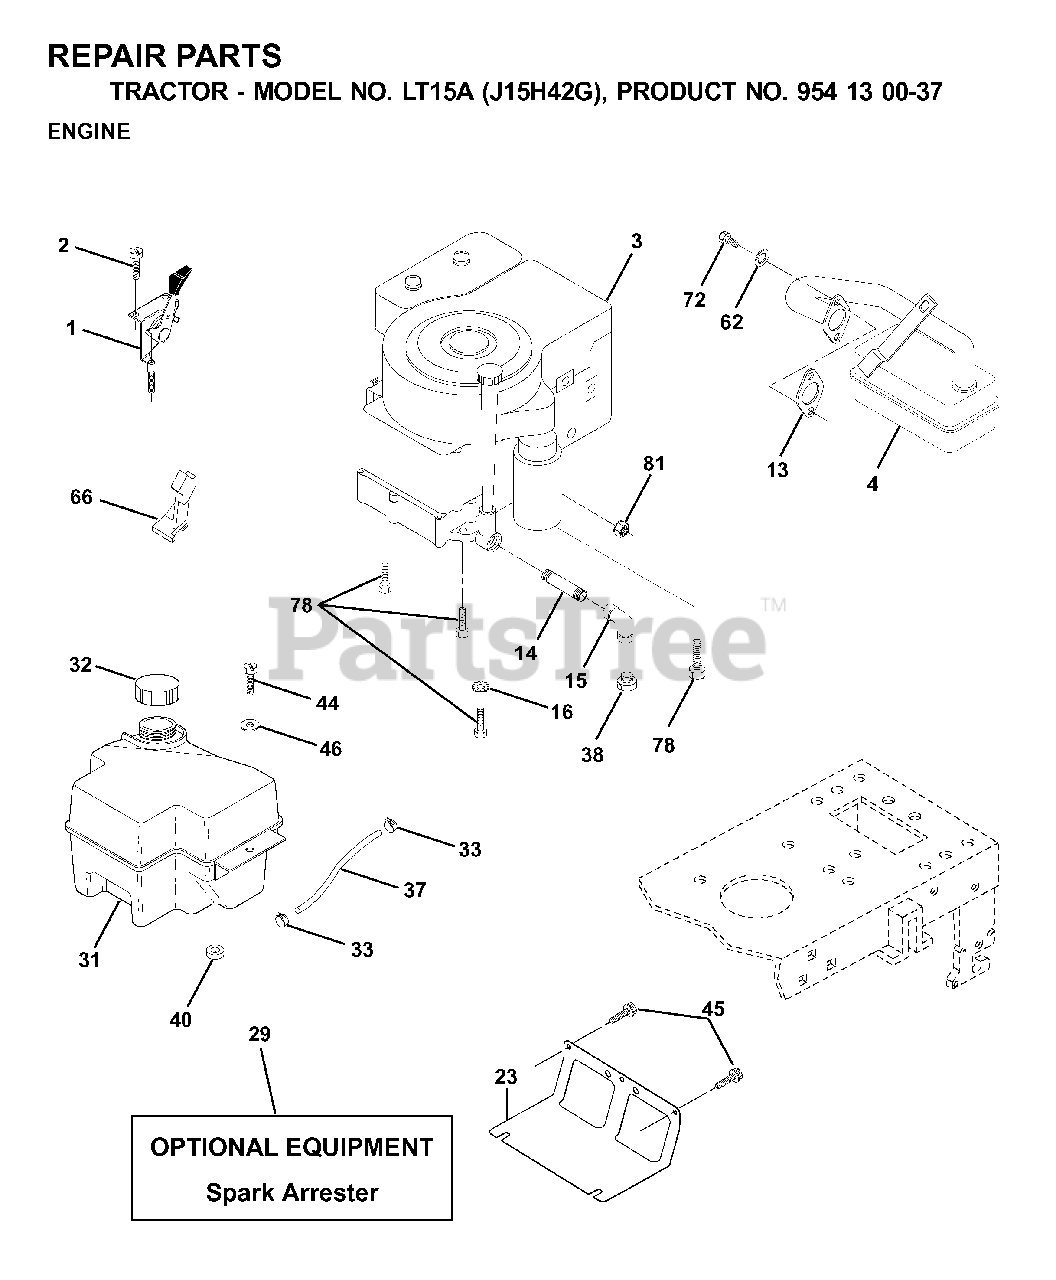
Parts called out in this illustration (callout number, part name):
1	CONTROL
2	SCREW LT
13	REPL BY 532 27 22-93
15	ELBOW
16	LOCKWASHER
23	SHEILD.BROWNING.DBR.GUARD
29	ARRESTER SPARK (OPTIONAL)
31	FUEL TANK
32	FUEL CAP
33	HOSE CLAMP
37	LINE.FUEL.20
40	GROMMET T
44	SCREW HEX CRT
45	SCREW 3/8-16X3/4
62	LOCKWASHER
66	STOP THROTTLE
72	SCREW
78	SCREW.3/8-16
81	NUT FLANGE 1/4-20 STARTER NUT
